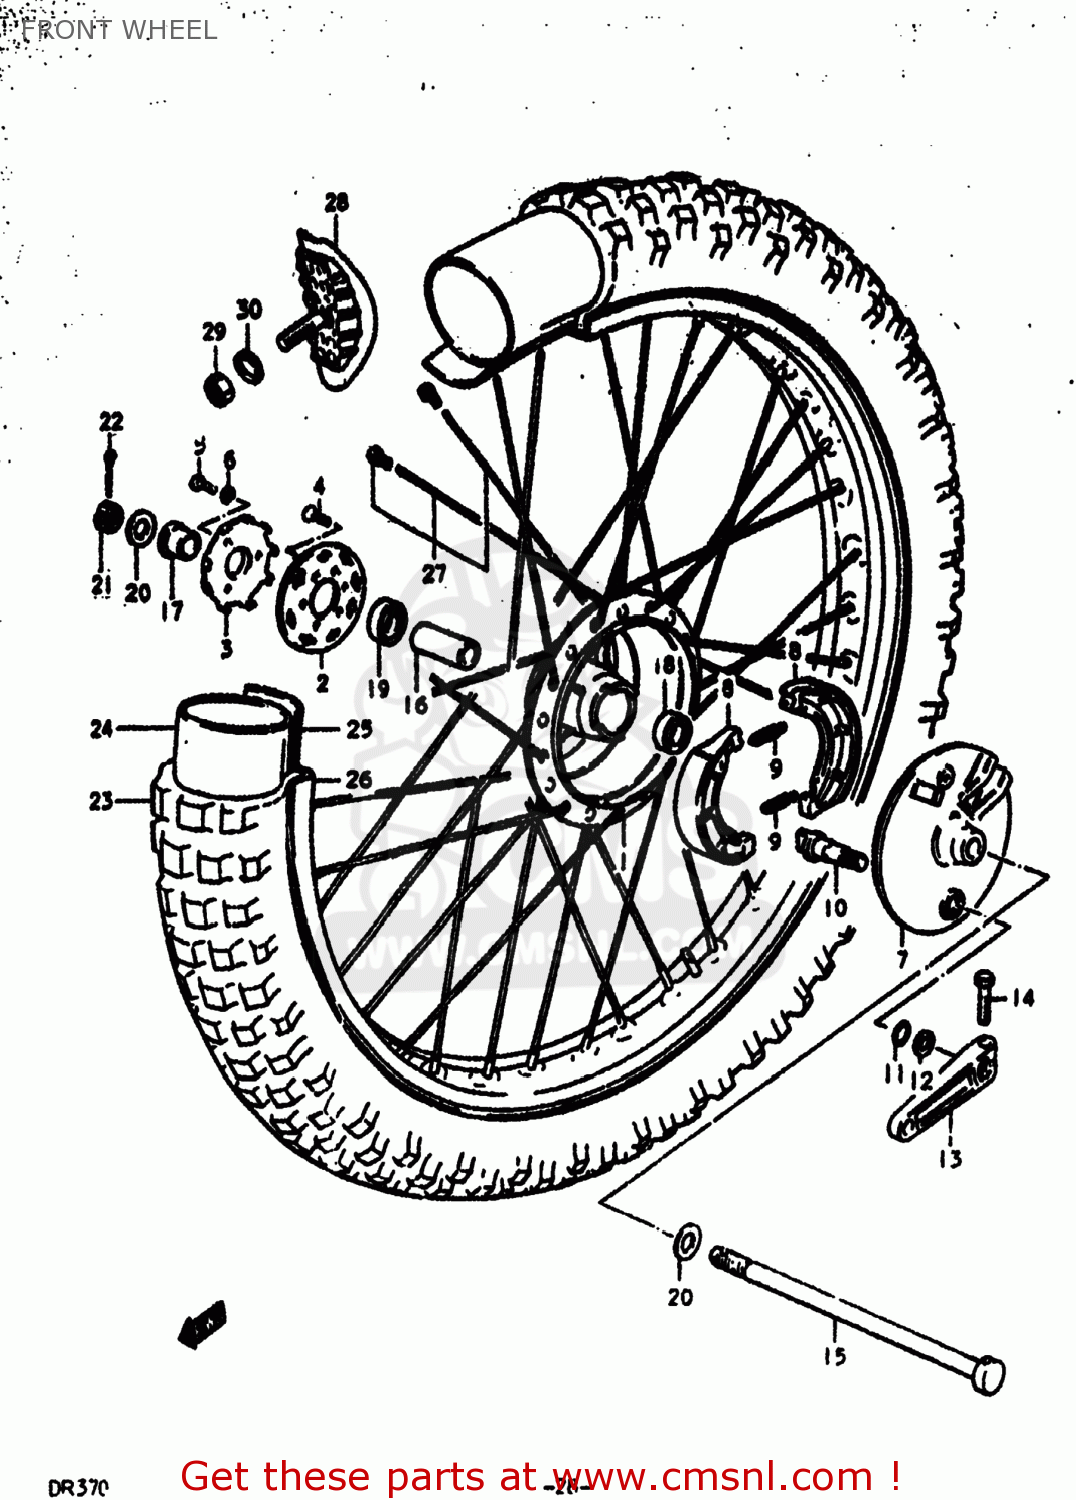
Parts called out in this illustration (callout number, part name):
1	HUB,FRONT
2	FLANGE,FRONT HUB,RIGHT
3	RETAINER,FR HUB BEARING,R
4	SCREW
5	BOLT, UPPER
6	LOCK WASHER
7	PANEL,FRONT HUB
8	SHOE,BRAKE
9	SPRING(L:34)
10	CAM,FRONT BRAKE
11	O RING(D:2.5,ID:11.4)
12	WASHER(12.5X20X1)
13	LEVER,FRONT BRAKE CAM
14	BOLT
15	AXLE,REAR
16	SPACER (12.6X19X52)
17	SPACER,FR AXLE,R
18	BEARING
19	BEARING
20	WASHER
21	NUT, REAR AXLE
22	COTTER PIN
23	TIRE,FRONT
24	TUBE
25	PROTECTOR,WHEEL,INNER
26	RIM,FRONT WHEEL
27	SPOKE SET,FRONT
28	STOPPER,BEAD
29	NUT
30	WASHER
